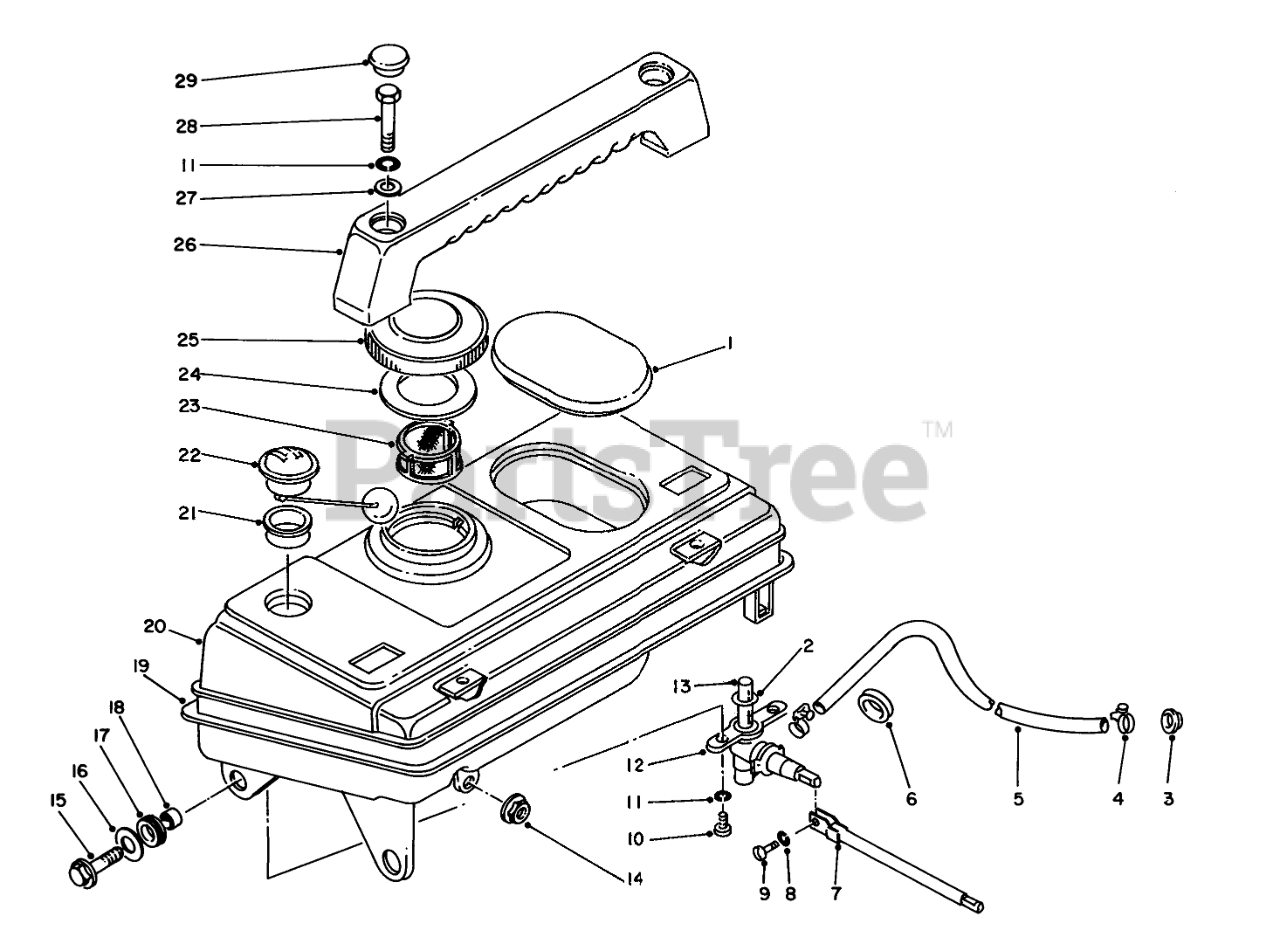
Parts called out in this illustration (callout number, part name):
3	Grommet
5	Hose-Fuel
6	Grommet
8	Lockwasher
9	SCREW
10	Screw
11	Washer-Lock
12	Cock Assembly-Fuel (Incl. Ref. #2 & 13)
16	WASHER
17	CUSHION
18	Spacer
19	Molding
20	Tank Assembly
21	Gasket
22	Gauge Assembly-Fuel (Incl. Ref. #21)
23	FILTER
24	GASKET
27	Washer
